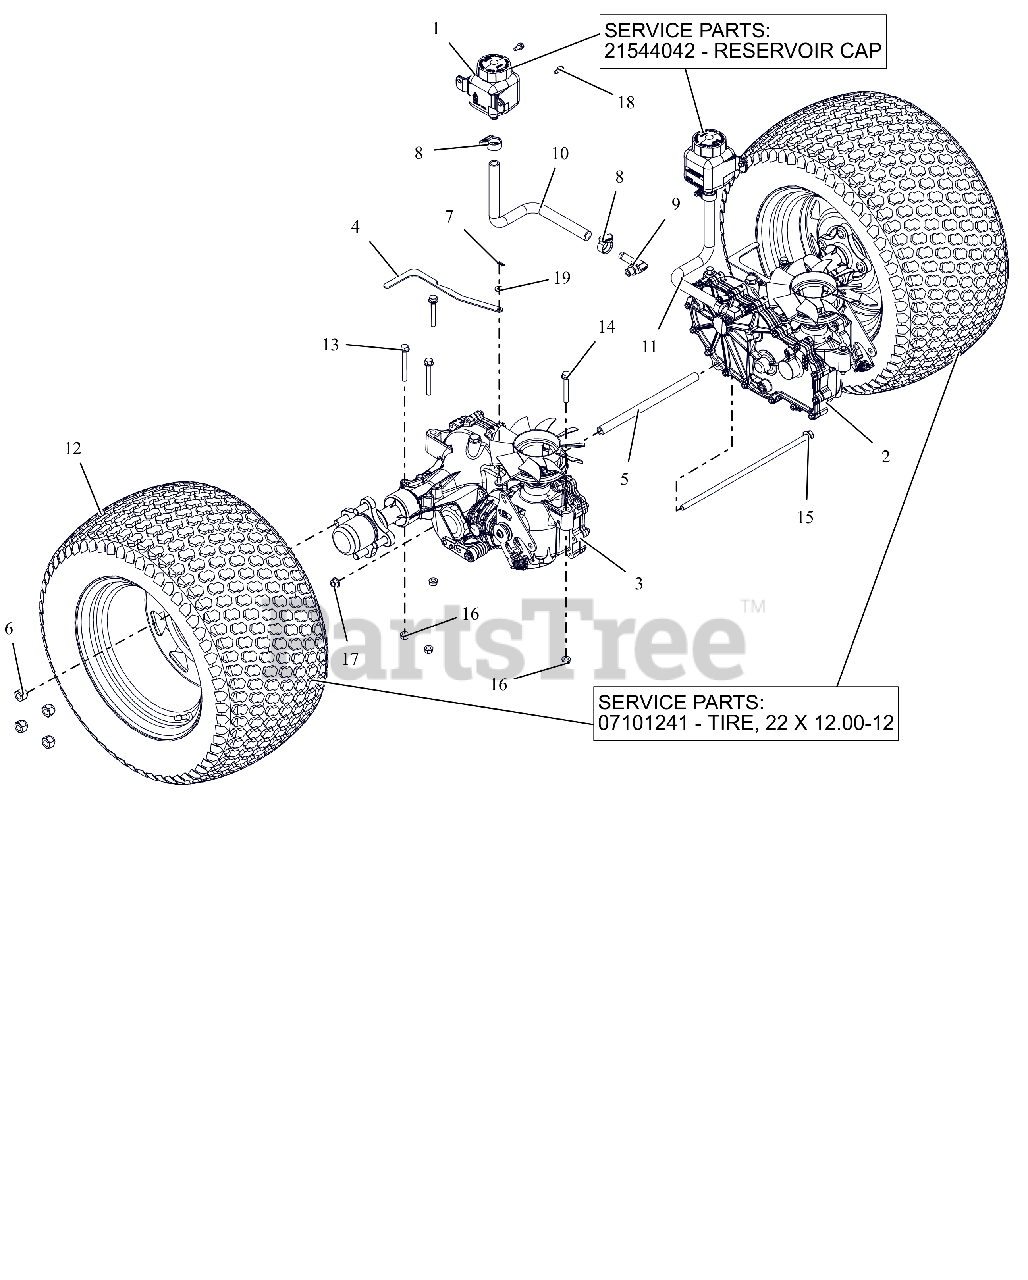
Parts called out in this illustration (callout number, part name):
1	TANK, EXPANSION
1	CAP, HYDRO RESERVOIR REPLAC.
2	TRANSAXLE, ZT3100 LH
3	TRANSAXLE, ZT3100 RH
4	BRKT, VALVE DUM
5	SPCR, TRANSAXLE .406 ID X .630 OD X 9.95LG (BLACK)
6	NUT, WHEEL .50-20 ZCC
7	PIN, HAIR #225 .072X1.09
8	CLAMP,.88 DIA. HOSE
9	FITTING, HYD (90 DEG)
10	HOSE, FORMED EXPANSION -HD RH
11	HOSE, FORMED EXPANSION -HD LH
12	ASM, WHL/TIRE 22X12.00-12 K500
12	TIRE, 22X12.00-12
13	BLT,HEX-FLG .31-18X2.75 G5 ZCC
14	BLT,HEX-FLG .31-18X2.25 G5 ZCC
15	BLT, HEX-FLG 0.375-16X13 GR5 ZC120
16	NUT,LK-CTR-FLG .31-18 GF ZCC
17	NUT-LK-CTR-FLG .375-16 GF ZCC
18	SCR-TAP .25-20X.50 HWH ZCC
19	WSHR,FLT .281X.625X.065 ZCC
